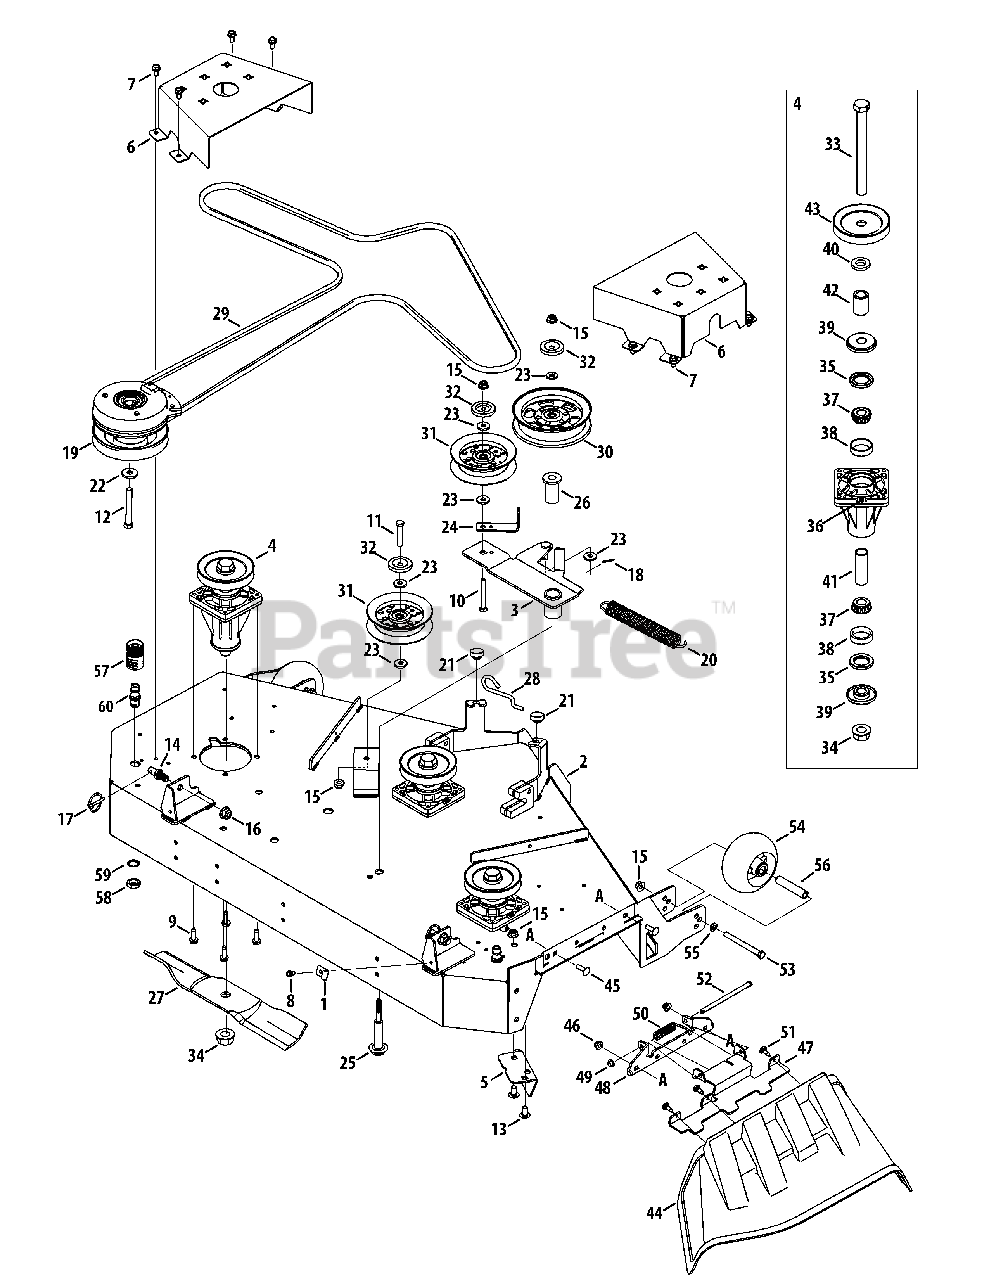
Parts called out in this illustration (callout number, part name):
1	Bracket, Hook Retainer
2	48" Deck FAB
3	Deck Idler Assembly
4	Spindle Assembly
6	Belt Cover
7	Hex Washer Screw, 5/16-18 x .750
8	Hex Washer Screw, 1/4-20 x .500
9	Hex Washer Screw, 5/16-18 x 1.250
10	Hex Cap Screw, 3/8-16 x 2.50
11	Hex Cap Screw, 3/8-16 x 2.00
12	Screw, 7/16-20 x 3.25
13	Carriage Screw, 3/8-16 x .75
14	Pin, Shoulder Lock, .500
15	Flange Lock Nut, 3/8-16
16	Flange Lock Nut, 1/2-13
17	Pin, Lynch x .1875
18	Cotter Pin 3/32" Dia. x .75 Lg.
19	Electric PTO Clutch
20	Extension Spring, 1.25 OD x 1.751
21	Rubber Bumper, 1.00 x .313
22	Flat Washer, .450 x 1.25 x .164
23	Flat Washer, .406 x .875 x .105
24	Belt Guard Bracket
25	Shoulder Boult, .625 x 2.12, 3/8-16
26	Shoulder Spacer, 1.055 x .627 x 2.292
27	Blade, 17.00
28	Deck Spring Rod
29	V-Belt
30	Idler Pulley, 5.00 Dia.
31	Idler Pulley, 4.00 Dia
32	Pulley Cap
33	Hex Cap Screw, 3/4-16 x 8.25
34	Nut, 3/4-16, Flangelock
36	Grease Fitting
37	Cone Bearing
38	Cup Bearing
39	Spindle Spacer
40	Spacer, .812 ID x .218 LG
41	Spacer, .78 x 1.00 x 2.895
42	Spacer, .792 x 1.20 x 1.628
43	V-Type Pulley
44	Discharge Chute Assembly
45	Carriage Bolt, 5/16-18 x 1.00
46	Flange Lock Nut, 5/16-18
47	Chute Bracket
49	Push Cap
50	Torsion Spring
51	Shoulder Screw, 1/4-20
52	Chute Rod
53	Hex Cap Screw, 3/8-16 x 4.0
54	Deck Ball Wheel, 5.0
55	Flat Washer, .406 x .875 x .059
56	Wheel Spacer
57	Water Nozzle Adapter
58	Hex Nut, M-16 x 1.5
59	Lock Washer, 17 x 23.8 x 1.95
60	Deck Water Nozzle
